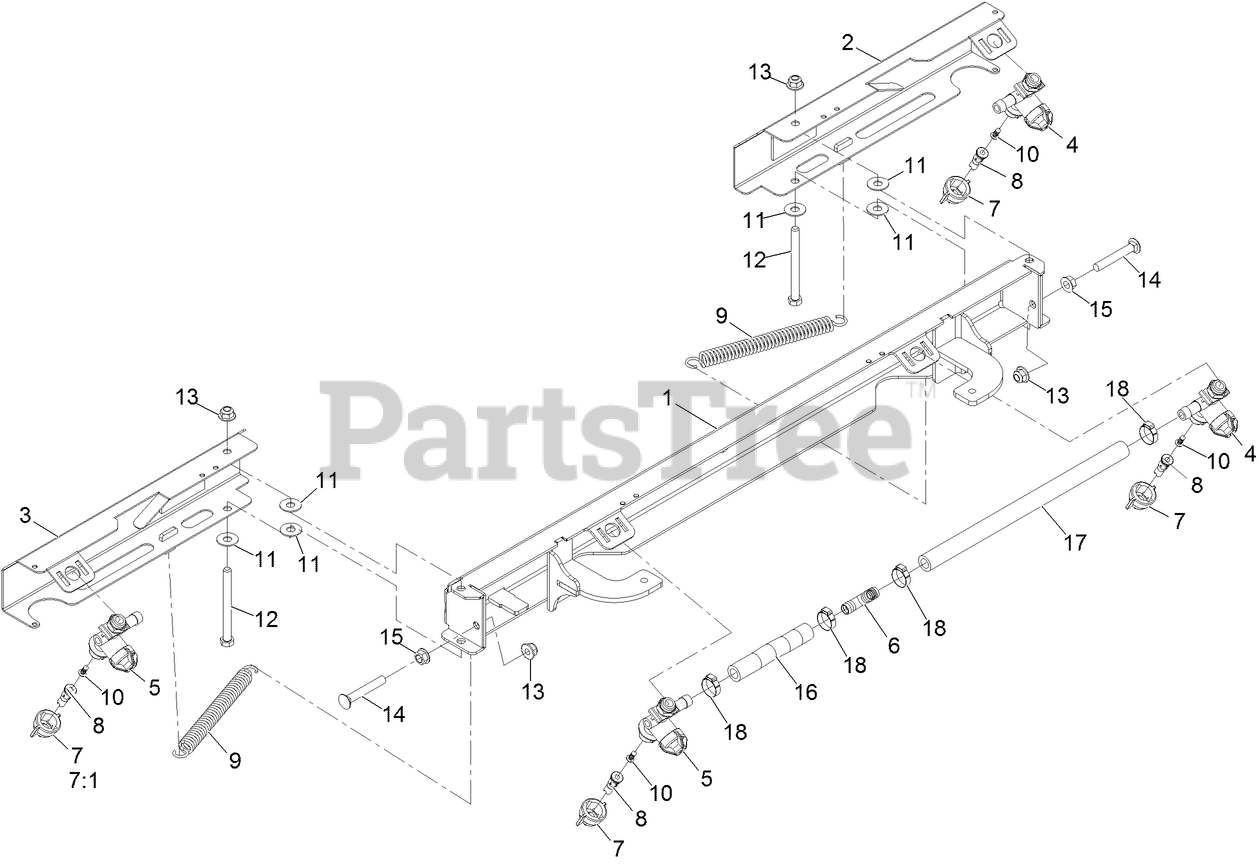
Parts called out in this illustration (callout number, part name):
1	Boom-Center
2	Boom-Wing, Rt
3	Boom-Wing, Lt
4	BODY-NOZZLE, RIGHT
5	BODY-NOZZLE, LEFT
6	FITTING-TEE, BARB
7	CAP-NOZZLE
7:1	SEAT-GASKET
8	TIP-SPRAY, 025
9	SPRING-EXTENSION
10	STRAINER-NOZZLE, 50M 5PSI
11	WASHER-FLAT
12	SCREW-HH
13	Nut-Hex Flange
14	SCREW-CARR
15	Nut-Hex Flange
16	Hose-Spray
17	Hose-Spray
18	CLAMP-OETIKER, 167
